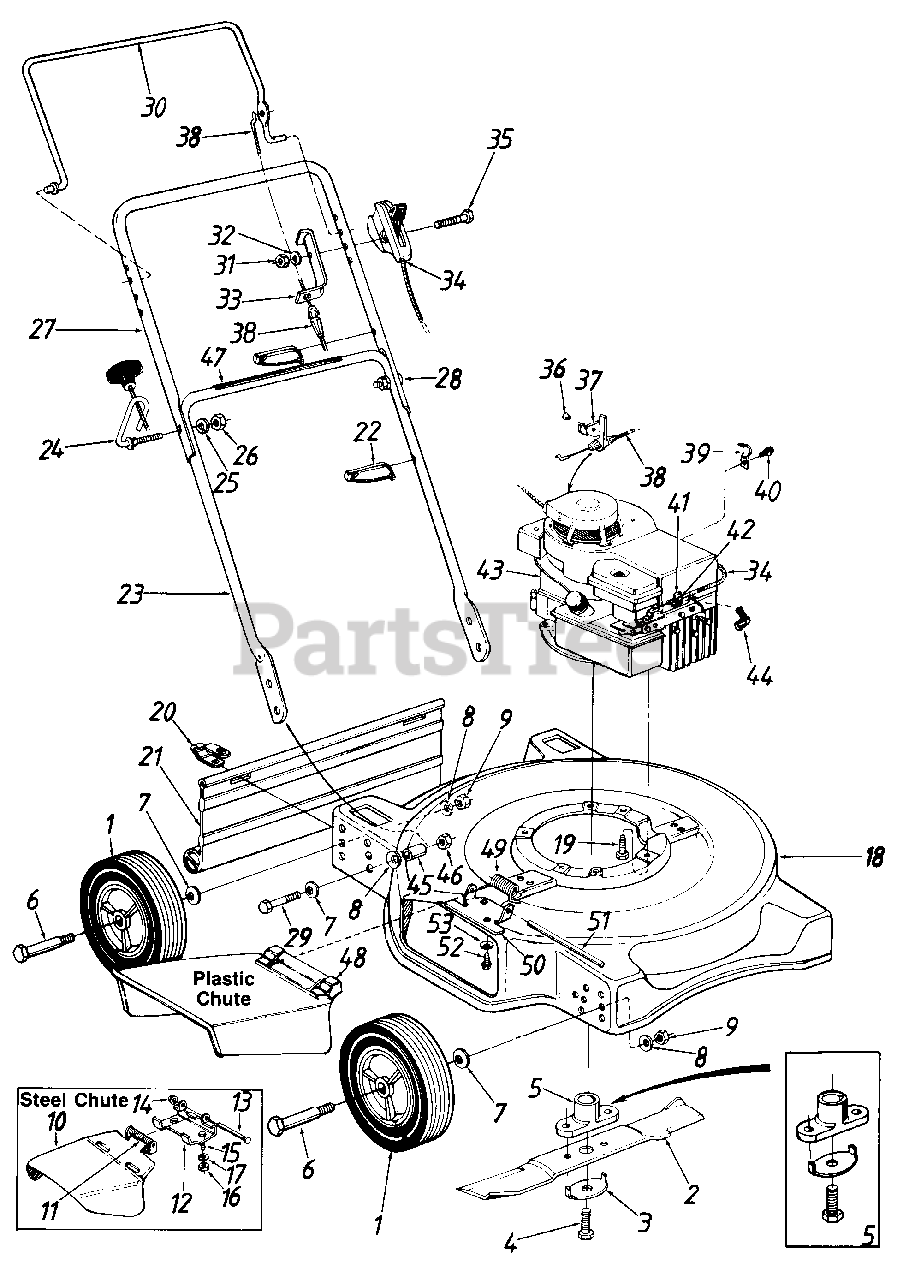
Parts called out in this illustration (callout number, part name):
1	Wheel Ass'y. Complete
2	20" Blade
3	Blade Bell-Washer
4	Hex Bolt 3/8-24 x 1.5" Lg.
5	Blade Adapter Kit (Keyed)
6	Shld. Bolt .498" Dia. x 1.64"
7	Bell-Wash. .380" I.D. x .88"
8	Bell-Wash. .39" I.D. x 1.13"
9	Hex Nut 3/8-16 Thd.
10	Chute Deflector Ass'y.
11	Torsion Spring
12	Adapter Plate
13	Pivot Pint
14	Speed Nut 1/4" Rod
15	Hex Bolt 1/4-20 x .5" Lg.
16	Hex Nut 1/4-20 Thd.
17	L-Wash. 1/4" I.D.
18	20" Deck Ass'y.
19	Hex Wash. Hd. Scr. 3/8-16 x 1" Lg.
20	Hinge Clip
21	Rear Flap 16.75" Lg.
22	Cable Tie
23	Lower Handle (Painted)
24	Rope Guide Bolt
25	L-Wash. 5/16" I.D.
26	Hex Nut 5/16-18 Thd.
27	Upper Handle (Painted)
28	Curved Carriage Bolt 5/16-18 x 1.38" Lg.
29	Hex Bolt 3/8-24 x 1.5" Lg.
30	Control Handle
31	Hex Nut 1/4-28 Thd.
32	Spr. Wash. .265" I.D. x .562"
33	Cable Mounting Bracket
34	Throttle Control Ass'y. Comp.
35	Hex Bolt 1/4-28 x 1.75" Lg.
36	Pop Rivet
37	Cable Bracket
38	Control Cable - 36"
39	Casing Clamp
40	Hex B-TaP Scr. #10 x .38" Lg.
41	Casing Clamp
42	Hex Wash. Hd. AB-Tap Scr. #8 x .50" Lg.
43	Engine
44	Spark Plug Boot
45	Spacer .381" I.D. x .56" O.D. x.75" Lg.
46	Hex L-Nut 3/8-24 Thd.
47	Instruction Label Handle
48	Chute Deflector Ass'y.
49	Torsion Spring
50	Adapter Plate
51	Hinge Pin
52	Hex Self-Tap Scr. 1/4-20 x .5" Lg.
53	Bell-Wash. 1/4" I.D.
